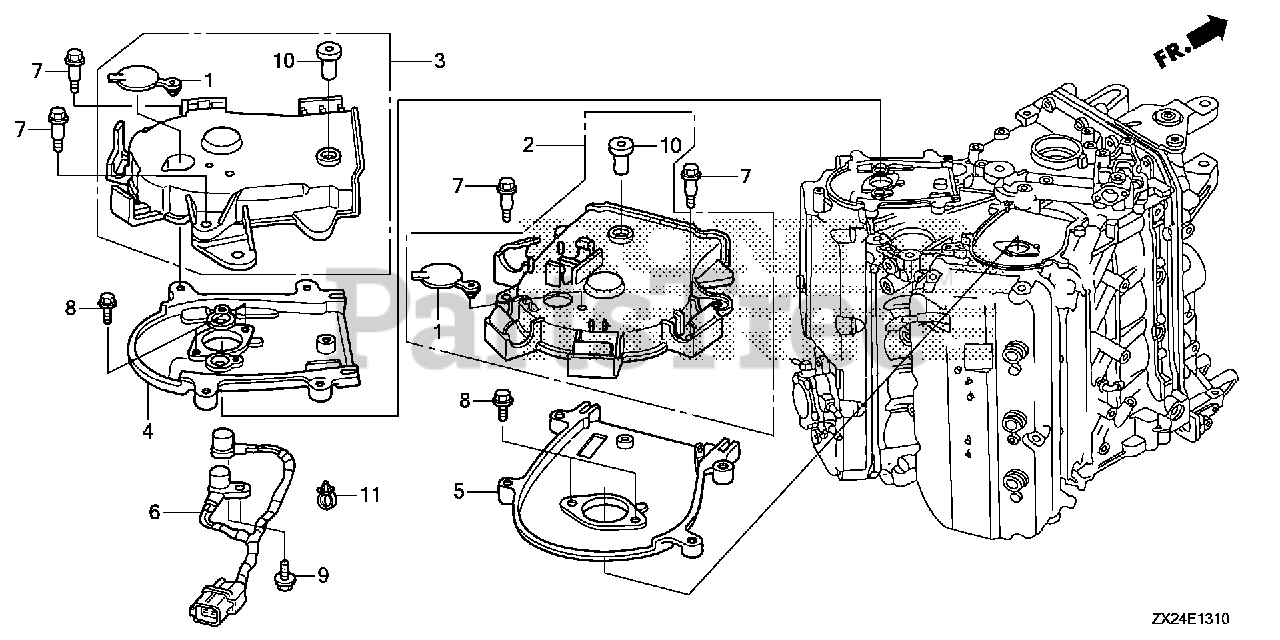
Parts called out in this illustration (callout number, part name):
1	GROMMET, TIMING BELT COVER
2	COVER ASSY., R. TIMING BELT
3	COVER ASSY., L. TIMING BELT
4	PLATE, L. TIMING BELT COVER
5	PLATE, R. TIMING BELT COVER
6	SENSOR (TDC1-TDC2)
7	BOLT, TIMING BELT COVER
8	BOLT, SPECIAL (8X29)
9	BOLT, FLANGE (5X14)
10	COLLAR, TIMING BELT COVER
11	CLIP, HARNESS BAND (145MM) (BLACK)
